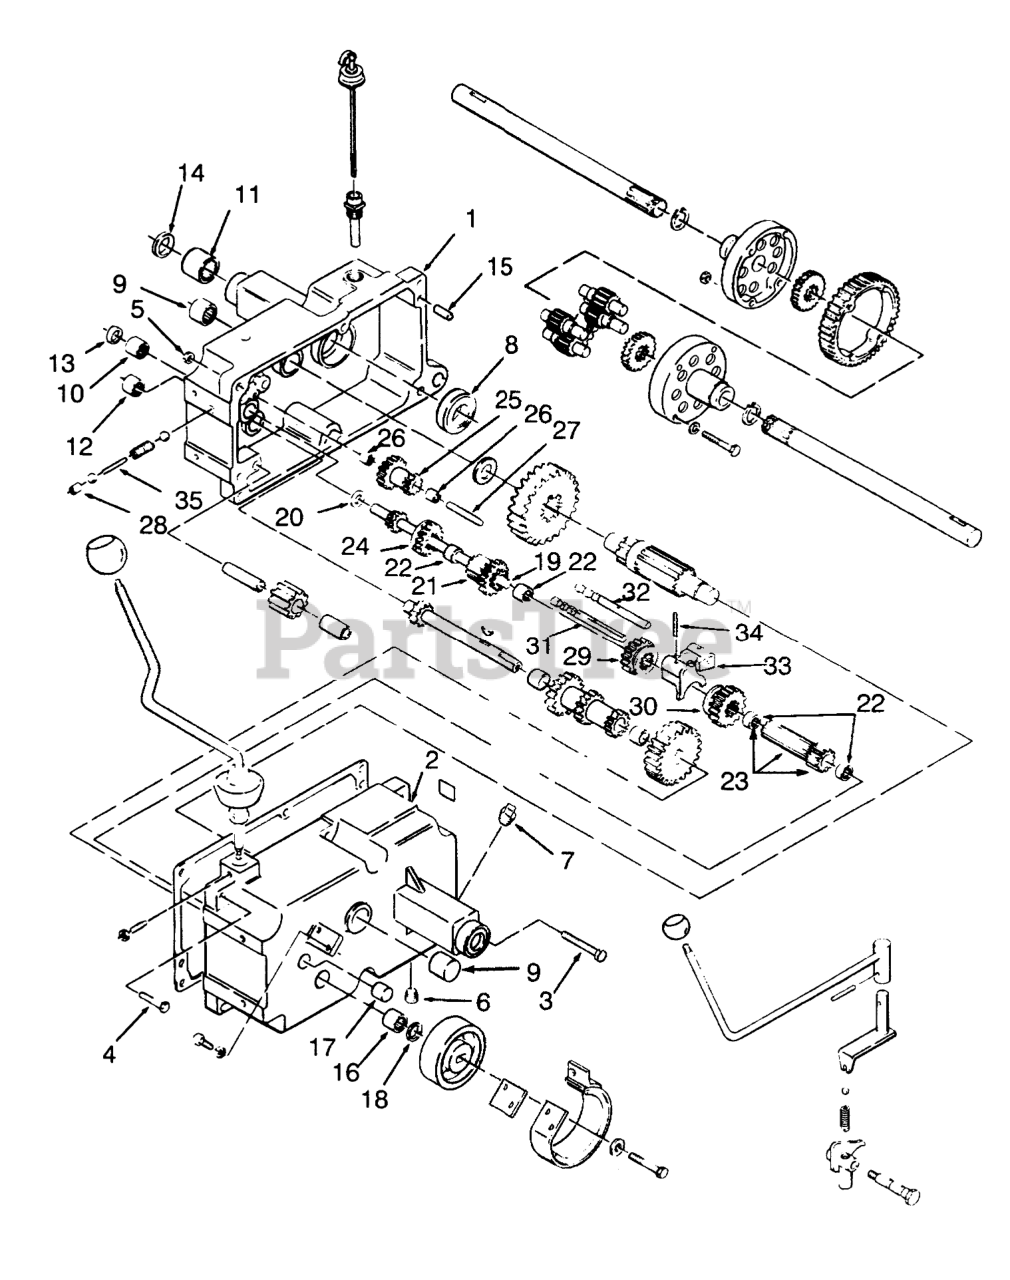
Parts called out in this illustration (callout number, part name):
1	Case Trans RH
2	Case Trans LH
3	SCREW-HH
4	SCREW-HH
5	NUT-LOCK, NI
7	PLUG-PIPE, SQH
8	BEARING-BALL
9	BEARING-NEEDLE
10	BEARING-NEEDLE
11	BEARING
12	BEARING-NEEDLE
13	SEAL-OIL
14	SEAL-OIL
15	PIN-DOWEL
16	BEARING-NEEDLE
17	BEARING-NEEDLE
18	SEAL-OIL
19	SHAFT-INPUT
20	WASHER-THR
21	Gear Assembly (Incl. Ref. #22)
22	BEARING-NEEDLE
23	Gear Assembly (Incl. Ref. # 22)
24	GEAR-SLIDING
25	Gear
26	BEARING-NEEDLE
27	GEAR-SHAFT REDUCTION
28	CUP-PLUG
29	GEAR-HI AND 2ND
30	GEAR-LOW AND REVERSE
31	RAIL-SHIFT
32	RAIL-REAR SHIFT
33	FORK-SHIFT
34	PIN-ROLL
35	PIN-SHIFT
